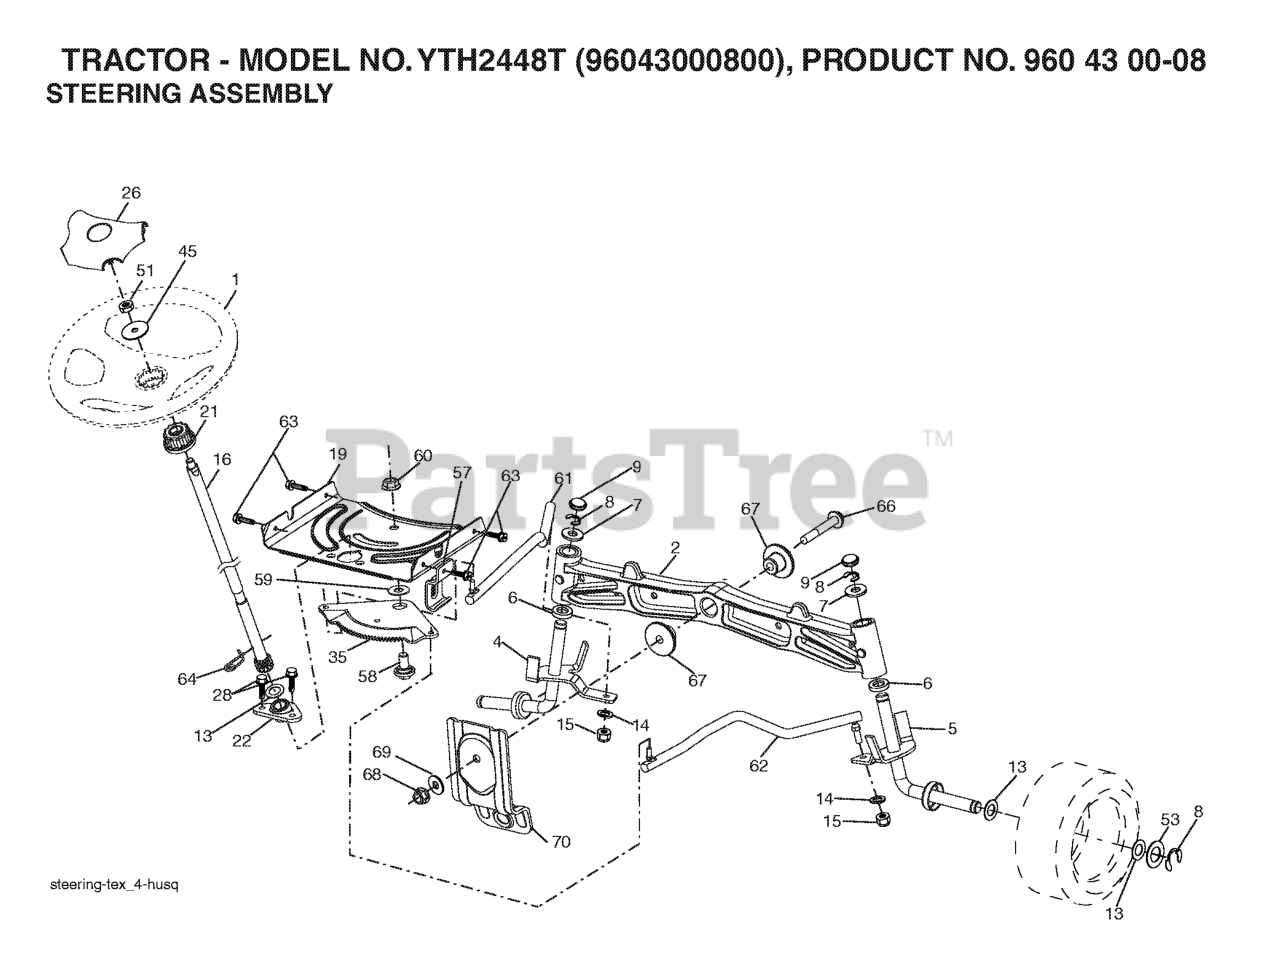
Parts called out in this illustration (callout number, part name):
1	WHEEL.STEERING.LEGEND2.GRY
2	AXLE.CAST.IRON
4	SPINDLE.ASM.LH.DDL
5	SPINDLE.ASM.RH.DDL
6	THRUST WASHER
9	CAP.SPINDLE.BLACK
14	WASHER, LOCK 3/8
15	NUT CROWNLOCK 3/8-24
16	SHAFT.STEER.STEALTH.DD
19	PLATE.STEER.DDL.NLT/NG
21	ADAPTER, WHEEL STNG..
22	BUSHING.ASM.STEERING.A
26	INSERT.CAP.STRG.WH.GRAY
28	SCREW, 3/8-16X3/4
35	GEAR.SECTOR.PLATE.DDL.
45	WASHER 9/16"ID, 2 3/8"OD
51	NUT.HEX.1/2-20
53	WASHER.HARDENED
57	BRKT.UPSTOP.GT/LT.TEX
58	BOLT.SHOULDER.SECTOR.P
59	WASHER.THURST.SECTOR.S
60	NUT FLANGE LOCK 5/8-11
61	DRAGLINK.LH.BALLSTUD.D
62	DRAGLINK.RH.BALLSTUD.D
63	SCREW
64	RETAINER.CLIP.SPRING.S
66	BOLT HEX FGHD 7/16-14 X 3 SERR
67	BUSHING.PM.FRONT AXLE
68	NUT.LOCK.FLANGE.7/16
69	WASHER.1.5X.505X.118
70	BRKT.DECK.SUSPENSION.F
